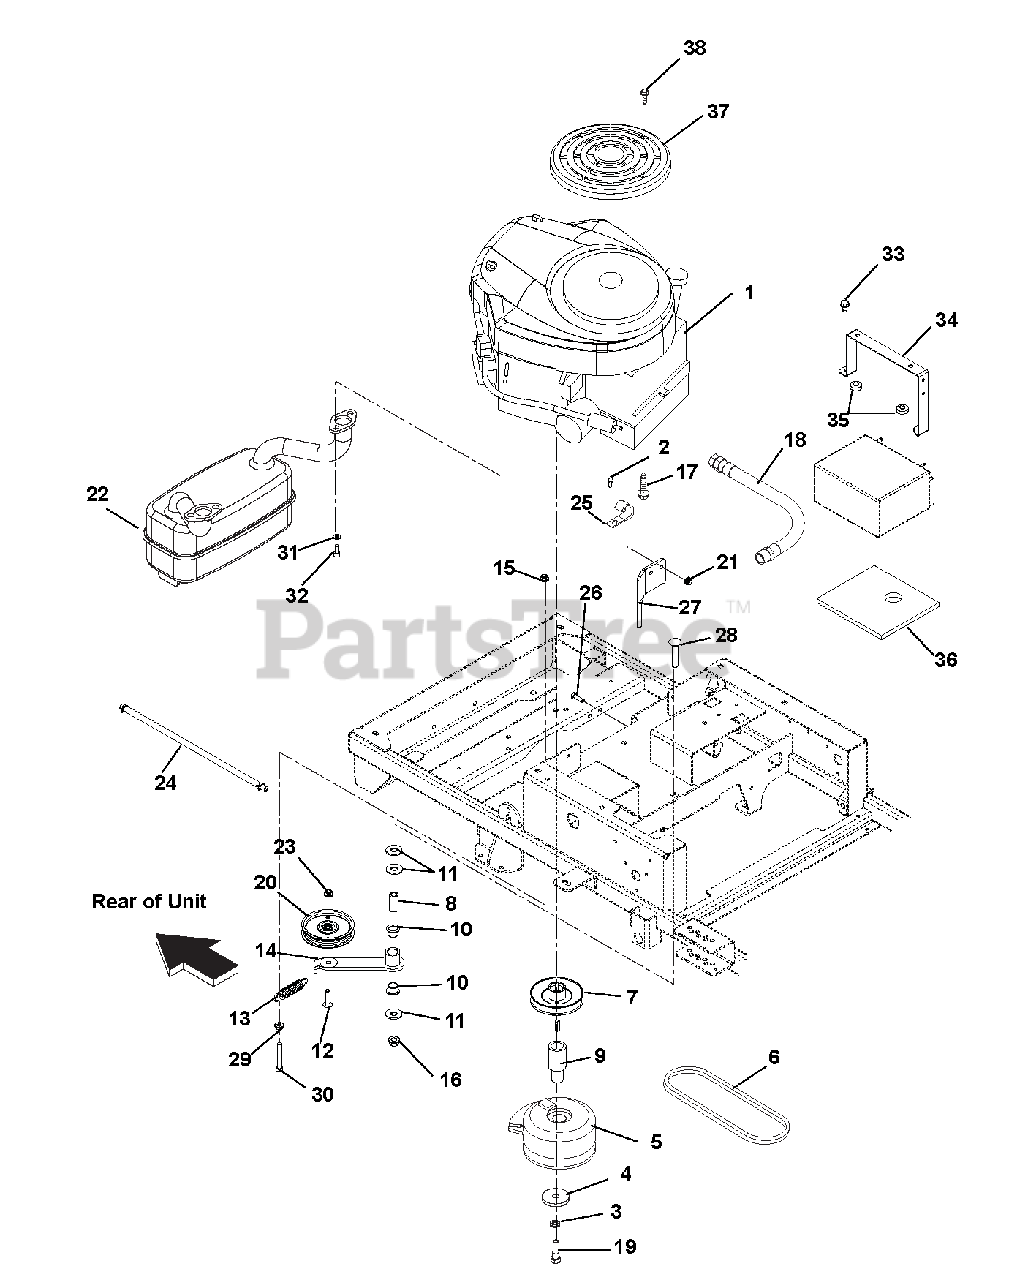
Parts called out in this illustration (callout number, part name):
1	ENGINE, 18HP BRIGGS ELS
1	ENGINE, BRIGGS 24HP ELS
1	ENGINE, 18HP V-TWIN CE
2	@SCR-TAP .25-20X.37 HWH YWZ TR
3	@WSHR-LK .44X.109 REG YWZC
4	WSHR-FL-STL .469X2.00X.25 YWZC
5	CLUTCH, MS
5	CLUTCH, MS WITH BRAKE
6	V-BELT, HA-WRAPPED
7	PLY-V 4.5X1.5 AB SECTION W/KEY
8	BSHG-SLV .500X.750X1.560
9	EXT-CRANKSHAFT LOWER
10	BSHG-FLG 0.75X0.875X.625X1.125
11	@WSHR-FL-STL.563X1.38X.109YWZC
12	@BLT-RDHDSQNK .38-16X1.50 G5YZ
13	SG-TENS .105X.812X3.88 WLD 15
14	WMT, GROUND DRIVE IDLER ARM
15	@NUT-LK-NYL-FLG .38-16 YWZC
16	@NUT-LK-TOP-FLG .50-13 YWZC
17	@SCR-TAP .38-16X1.00 HWH TR YZ
18	HOSE, HYD .38-11-0K M6N0-F6J0
19	BLT-HEX .44-20X4.50 GR8 YWZC
20	ASM, 4" IDLER (.75 WIDE)
21	@NUT-LK-NYL-FLG .31-18 YWZC
22	MUFFLER - TWIN BRIGGS
23	@NUT-LK-TOP-FLG .38-16 YWZC
24	ASM, FUEL HOSE
25	J-CLAMP
26	@BLT-HEX .31-18X1.00 GR5 YWZC
27	CLUTCH STOP
28	@BLT-RDHDSQNK .50-13X2.50 G5YZ
29	@NUT-SPNLK-FLG .375-16 YWZC
30	@BLT-HEX .38-16X2.50 GR5 YWZC
31	@WSHR-LK .31X.078 REG YWZC
32	SCR-CAP .31-18X.75 S/HD
33	SCR-TAP.250-20X.62 HWH BLK ZC
34	STRAP, BATTERY
35	BUTTON BUMPER
36	MAT, BATTERY
37	GUARD, BRIGGS ENGINE
38	SCREW, 8-16X.87 PHPAN 3 LOBE
